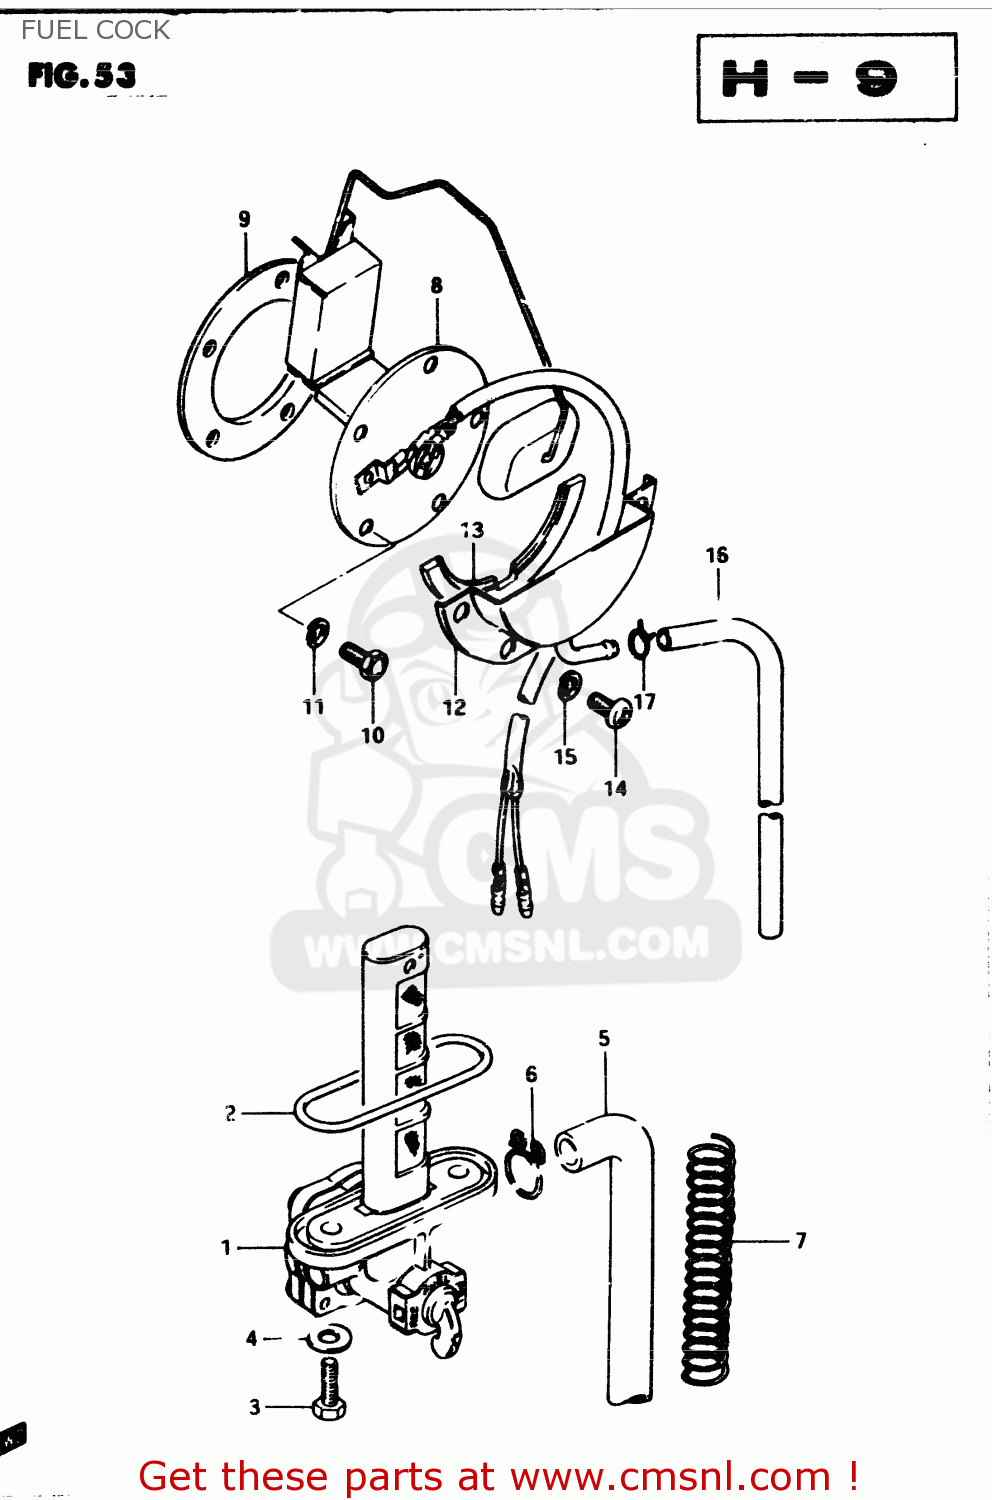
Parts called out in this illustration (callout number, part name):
1	COCK ASSEMBLY,FUEL
2	O RING
3	SCREW
4	GASKET
5	HOSE
6	CLIP
7	SPRING
8	GAUGE ASSEMBLY,FUEL LEVEL
9	GASKET,FUEL LEVEL GAUGE (NAS)
10	BOLT 5X10
11	LOCK WASHER
12	PLATE,FUEL DRAIN
13	GASKET (NAS)
14	SCREW
15	LOCK WASHER
16	HOSE,FUEL
17	CLIP
